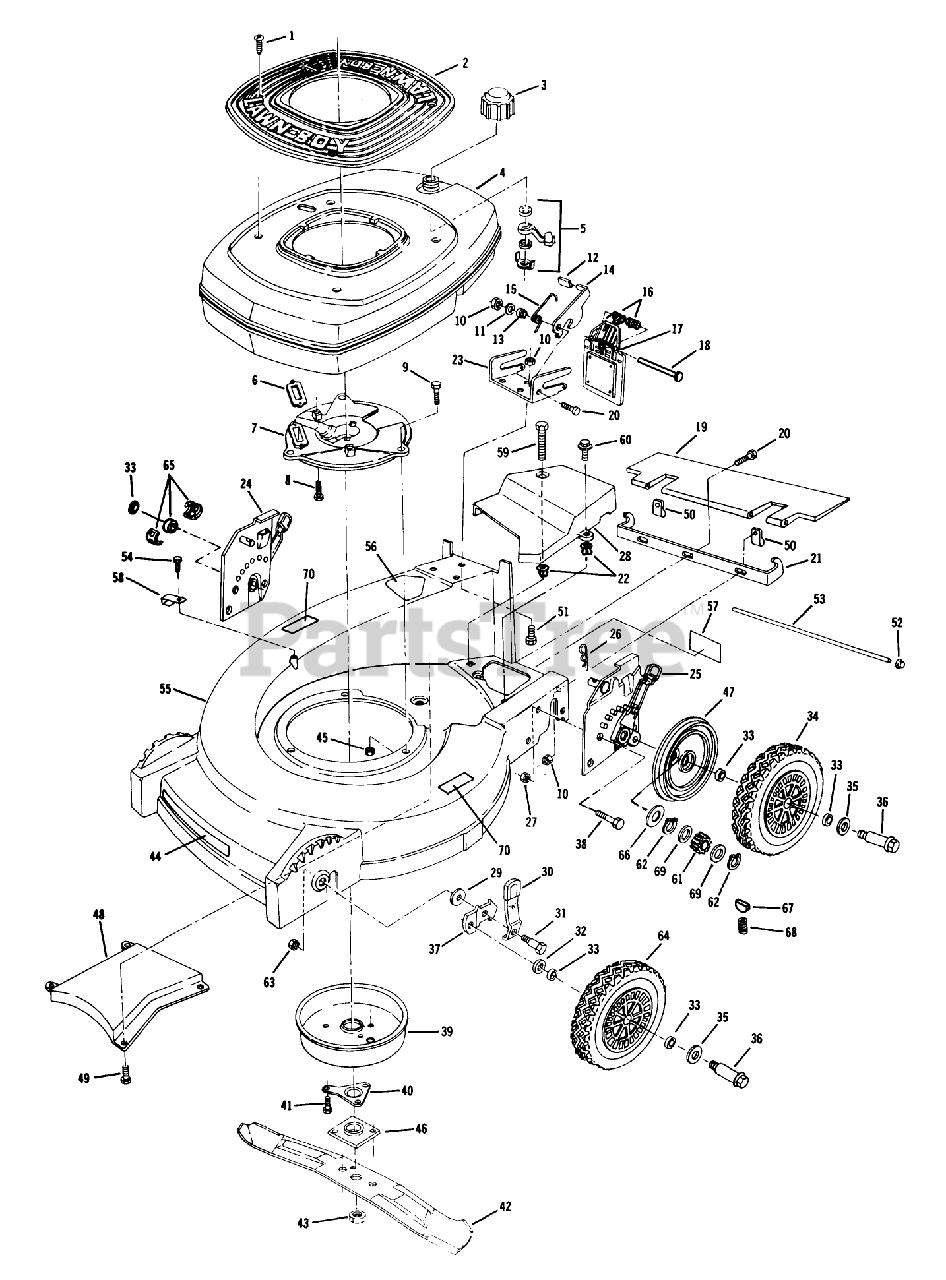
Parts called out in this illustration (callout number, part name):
1	SCREW - SELF TAPPING
3	FUEL CAP & INSERT
5	SHUT-OFF VALVE S
7	PLATE F
8	SCREW V
9	SCREW-HH
10	LOCKNUT E
16	SPRING ASOC
18	ROD (RB&W)
19	T/SHIELD SM&P
25	HEIGHT ADJUSTER AY
26	HAIR PIN
27	NUT-LOCK F
32	WASHER WROUGHT
36	BOLT WHEEL
39	MUFFLER COVER F
40	SUPPORT F
43	NUT-BLADE
45	NUT-LOCK F
46	PLATE AND COLLAR ASM
48	BAFFLE CHUTE PL
54	SCREW LAWRENCE
61	PINION BROCKWAY
62	RET RING
63	LOCKNUT
64	WHEEL&TIRE 8" TRI
65	REAR AXLE BEARING
66	THRUST WASHER
69	SPACER/GR ALGHNY
